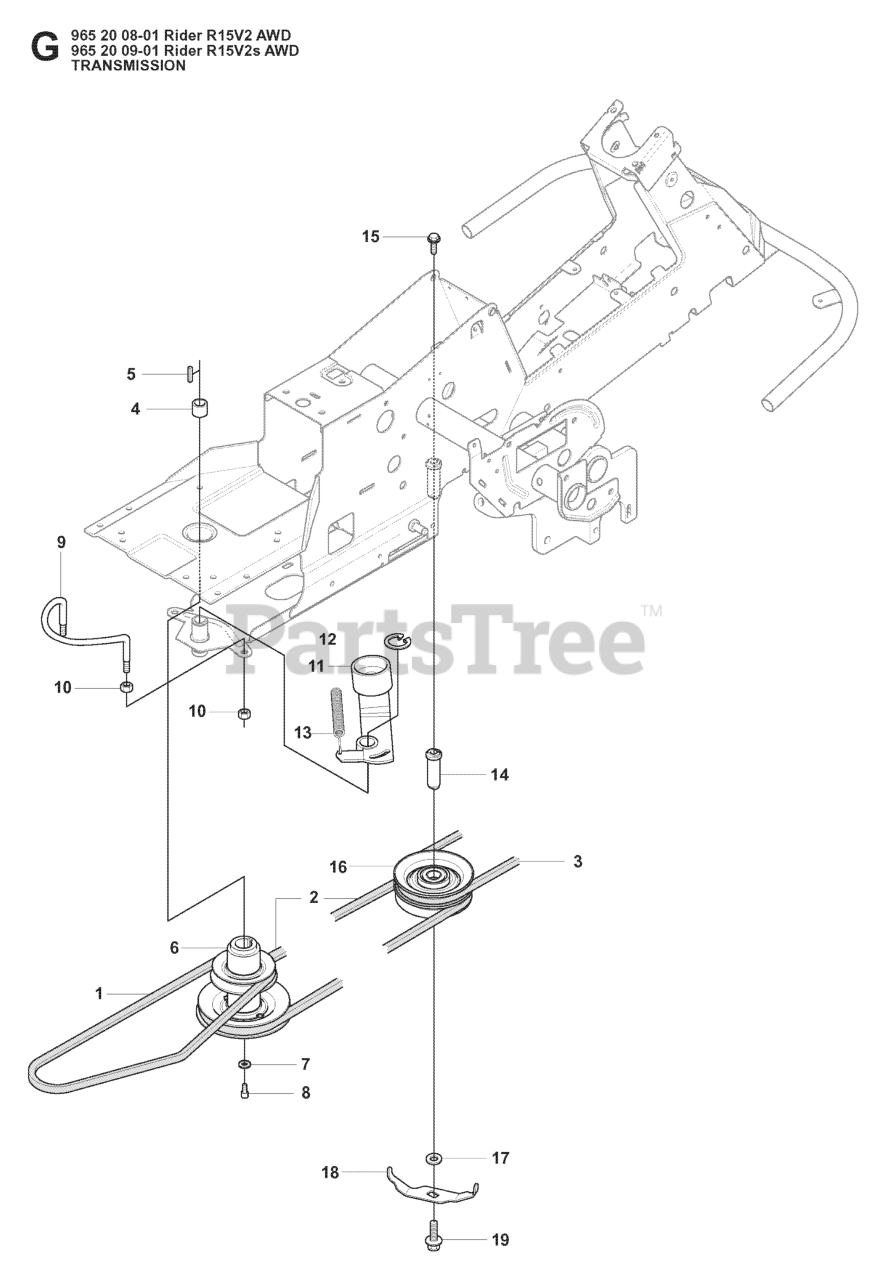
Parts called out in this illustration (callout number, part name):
9	BELT GUIDE
10	NUT
12	RETAINING RING SGA 25
14	SHAFT
18	BELT GUIDE
19	BOLT
